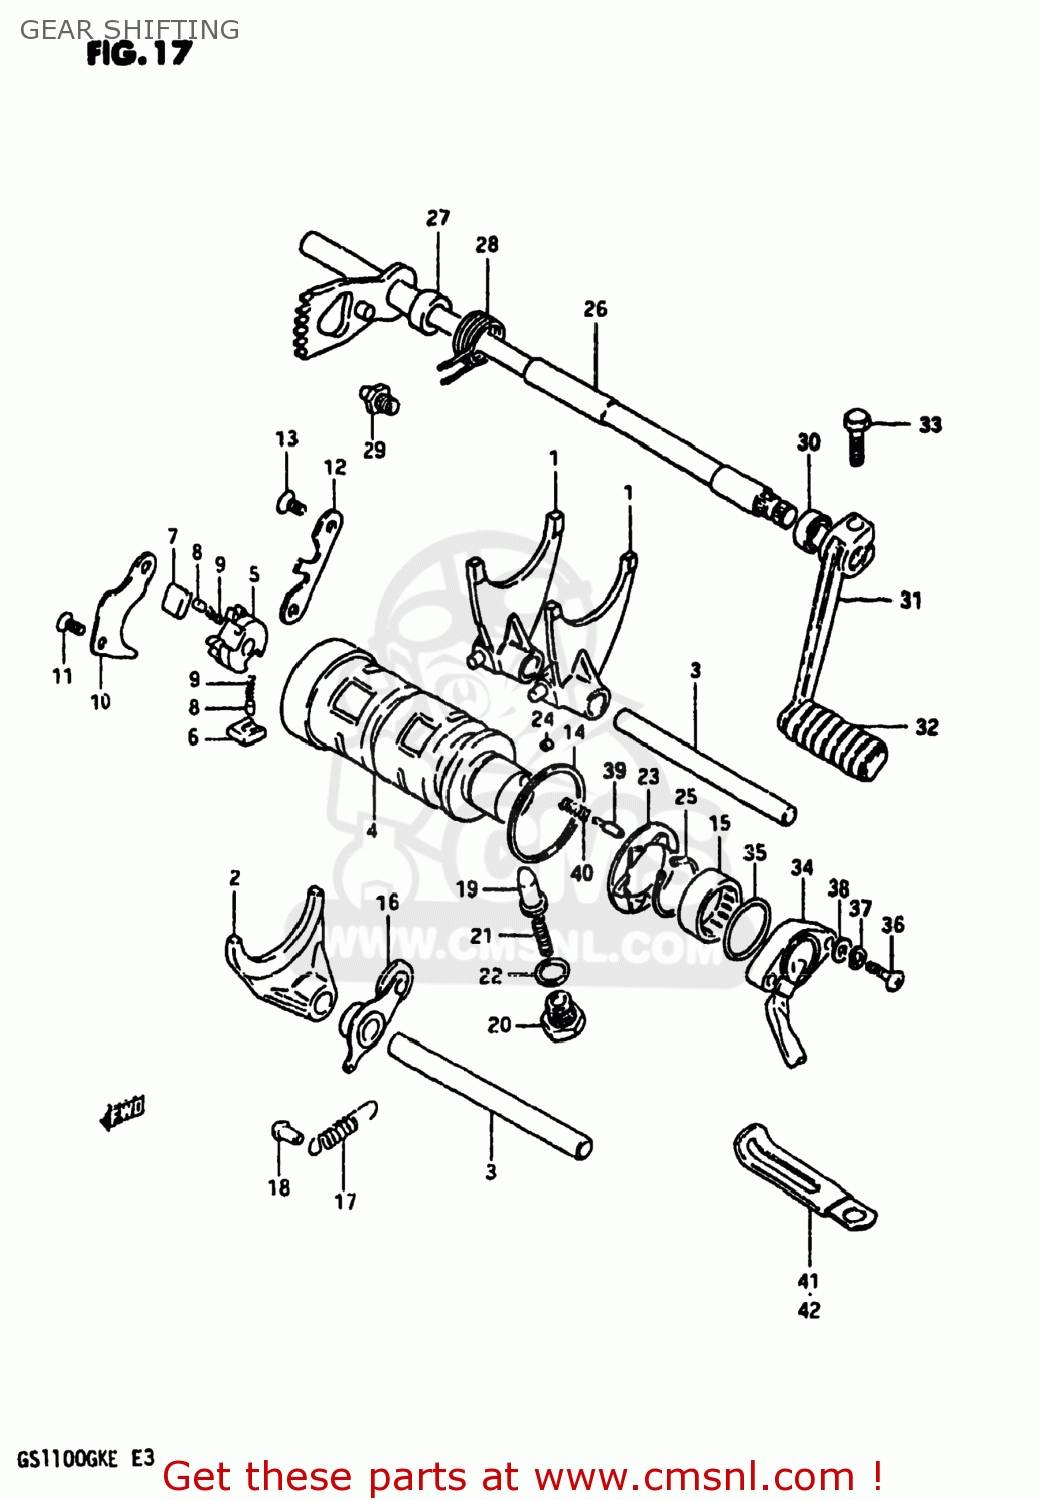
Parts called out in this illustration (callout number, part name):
1	FORK,GEAR SHIFT NO.1
2	FORK,GEAR SHIFT NO.3
3	SHAFT,GEAR SHIFT FORK
4	CAM,GEAR SHIFT
5	SHIFTER,GEAR SHIFT CAM
6	PAWL,GEAR SHIFT NO.1
7	PAWL,GEAR SHIFT NO.2
8	PIN(5X8)
9	SPRING
10	LIFTER,GEAR SHIFT PAWL
11	SCREW
12	GUIDE,GEAR SHIFT CAM
13	SCREW
14	WASHER(40X45X1)
15	BEARING(25X32X12)
16	STOPPER,GEAR SHIFTING
17	SPRING
18	RIVET
19	STOPPER,GEAR SHIFT CAM NO.2
20	HOLDER,GEAR SHIFT CAM STOP SPR
21	SPRING
22	GASKET(14X19.2X2) (NAS)
23	PLATE,GEAR SHIFT CAM STOPPER
24	PIN 4X6
25	CIRCLIP,25MM
26	SHAFT,GEAR SHIFT
27	SPACER (12X20X12)
28	SPRING
29	STOPPER,GEAR SHIFT CAM
30	OIL SEAL
31	LEVER ASSEMBLY,GEAR SHIFTING
32	RUBBER,PEDAL
33	BOLT
34	TERMINAL BASE ASSY,GEAR SHIFT
35	O-RING (D:2.4 ID:26.2)
36	SCREW 5X20
37	LOCK WASHER
38	WASHER
39	PIN(5X15.5)
40	SPRING
41	CLAMP
42	CLAMP
